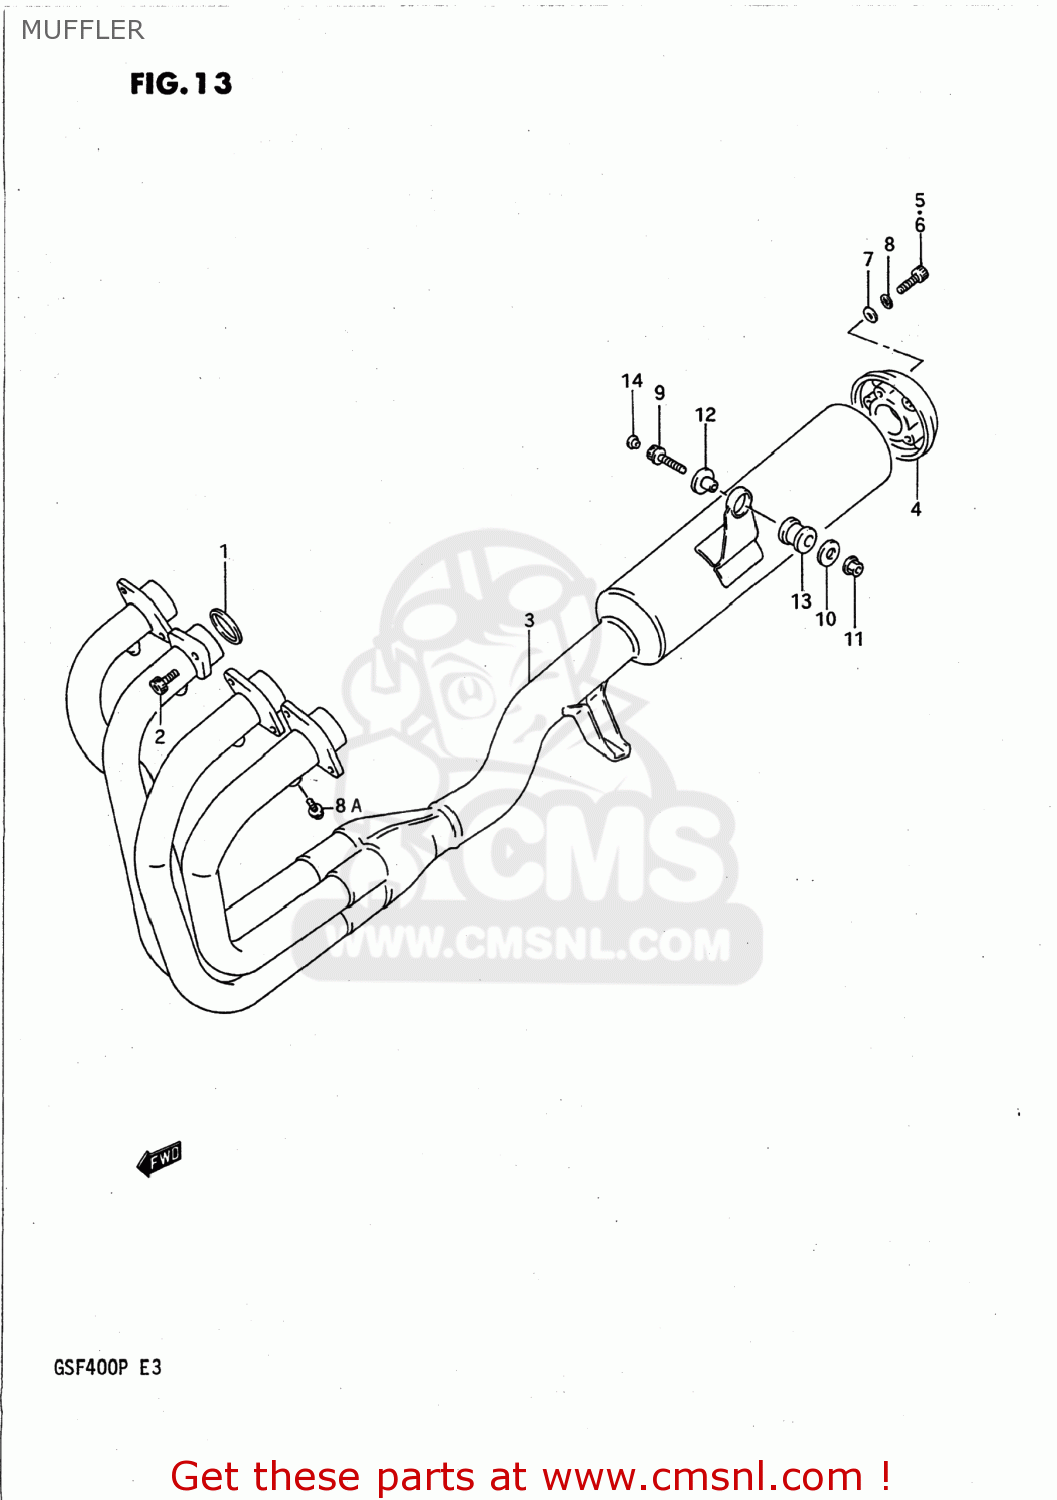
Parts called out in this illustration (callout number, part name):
1	GASKET,EXHAUST PIPE (NAS)
2	BOLT 8X23
3	MUFFLER ASSEMBLY
4	COVER,MUFFLER
5	BOLT(6X10)
6	BOLT
7	WASHER(7X12X1)
8	WASHER
8A	BOLT, DRAIN
9	BOLT
10	WASHER (8.5X29X1.6)
11	NUT
12	SPACER(8.6X12X24.2)
13	CUSHION
14	CAP(OD:10)
